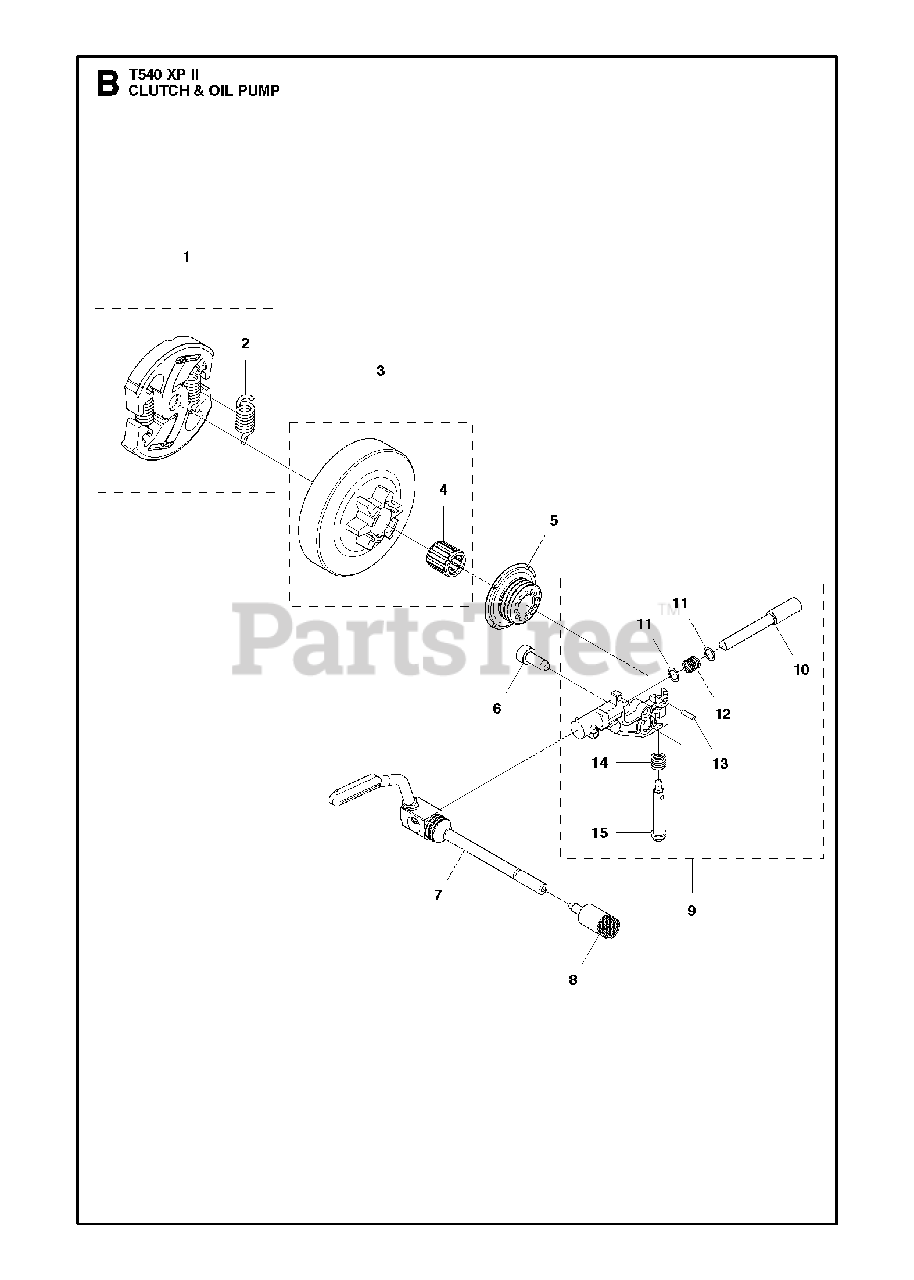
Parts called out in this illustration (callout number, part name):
1	CLUTCH ASSY
2	CLUTCH SPRING
3	CLUTCH DRUM ASSY KIT
4	NEEDLE BEARING
5	WORM WHEEL
6	SCREW ITXSCT
8	OIL PLUMMET
9	OIL PUMP ASSY
10	PUMP PISTON
11	WASHER
12	SPRING
13	PIN
14	SPRING
15	ADJUSTER
